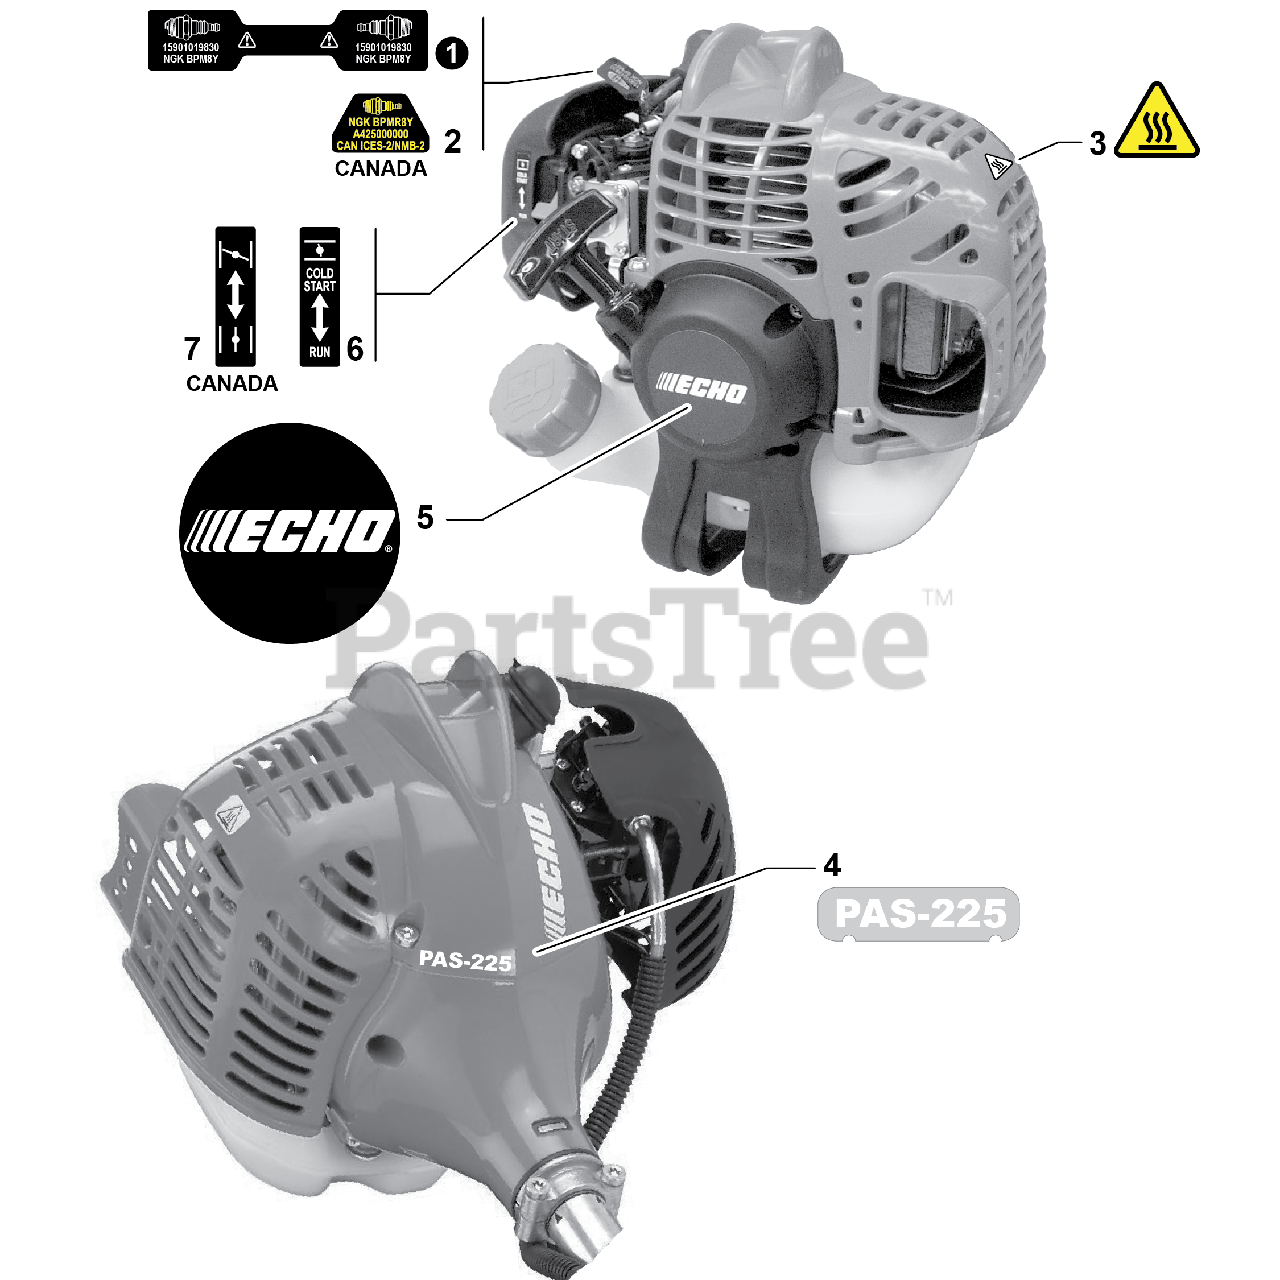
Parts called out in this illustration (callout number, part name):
1	LABEL, SPARK PLUG - BPM8Y
2	LABEL, SPARK PLUG - BPMR8Y
3	LABEL, CAUTION - HOT
4	LABEL, MODEL - PAS-225
5	LABEL, RECOIL STARTER
6	LABEL, CHOKE
7	LABEL, CHOKE
